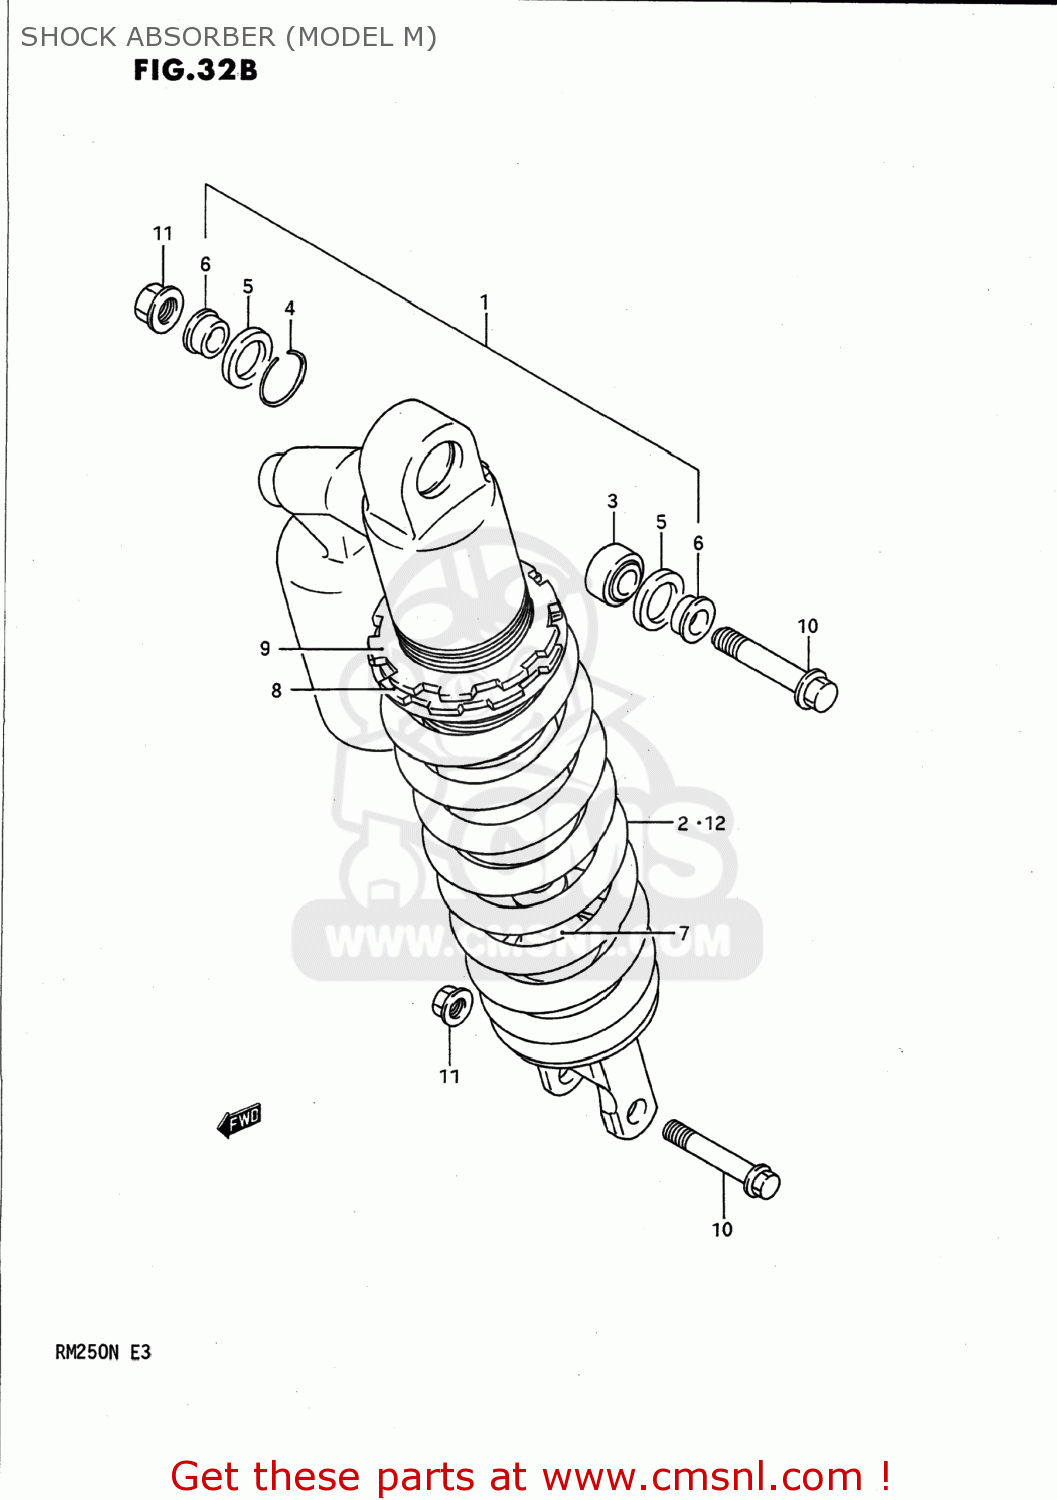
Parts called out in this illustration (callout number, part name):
1	ABSORBER ASSEMBLY,REAR SHOCK
2	SPRING
3	BEARING,REAR SHOCK ABSORBER
4	RING,STOPPER
5	SEAL,DUST
6	COLLAR
7	ROD,PISTON
8	GUIDE,SPRING
9	NUT
10	BOLT,REAR SHOCK ABSORBER
11	NUT
12	SPRING,REAR (K=5.4)
